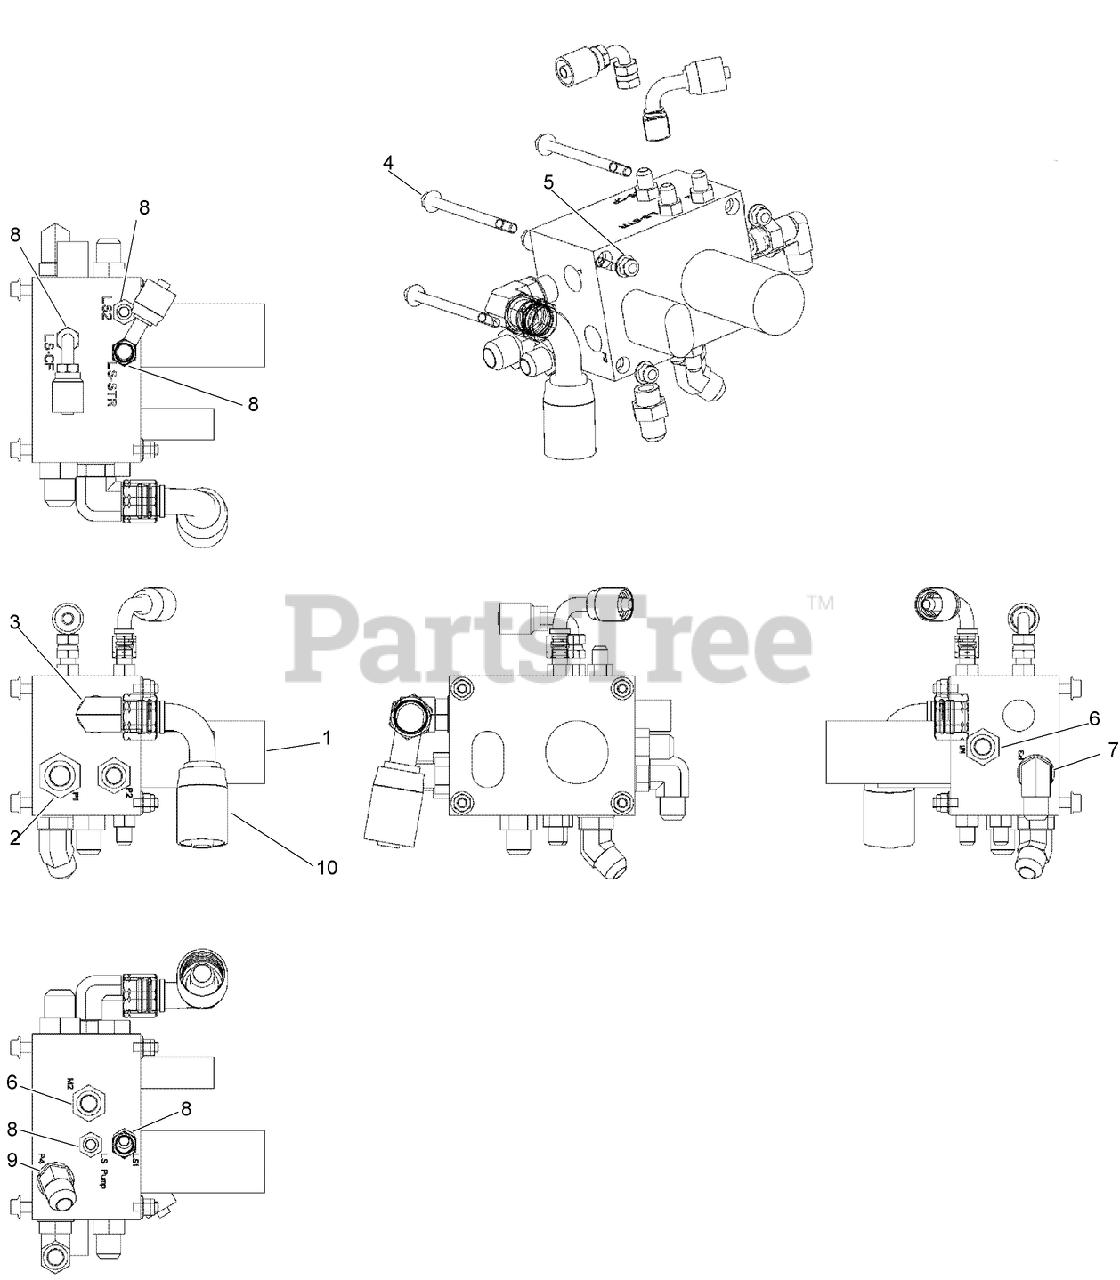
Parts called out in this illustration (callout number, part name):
1	VALVE-FAN DRIVE
2	FITTING-STRAIGHT
3	ELBOW-90 Adj 37FL 3/4 x 5/8 Tube
4	SCREW, METRIC FLANGE w/BODY - M8 x 110
5	NUT-TORQUE, PREVAILING
6	CONNECTOR-Str Thd 5/8, 37FL-ORB 5/8
7	ELBOW-90 Adj 37FL 5/8 Tube
8	CONNECTOR-Str Thd 3/8, 37FL-ORB 3/8
9	FITTING-ELBOW-45 DEG
10	KIT, Hydraulic Hoses
